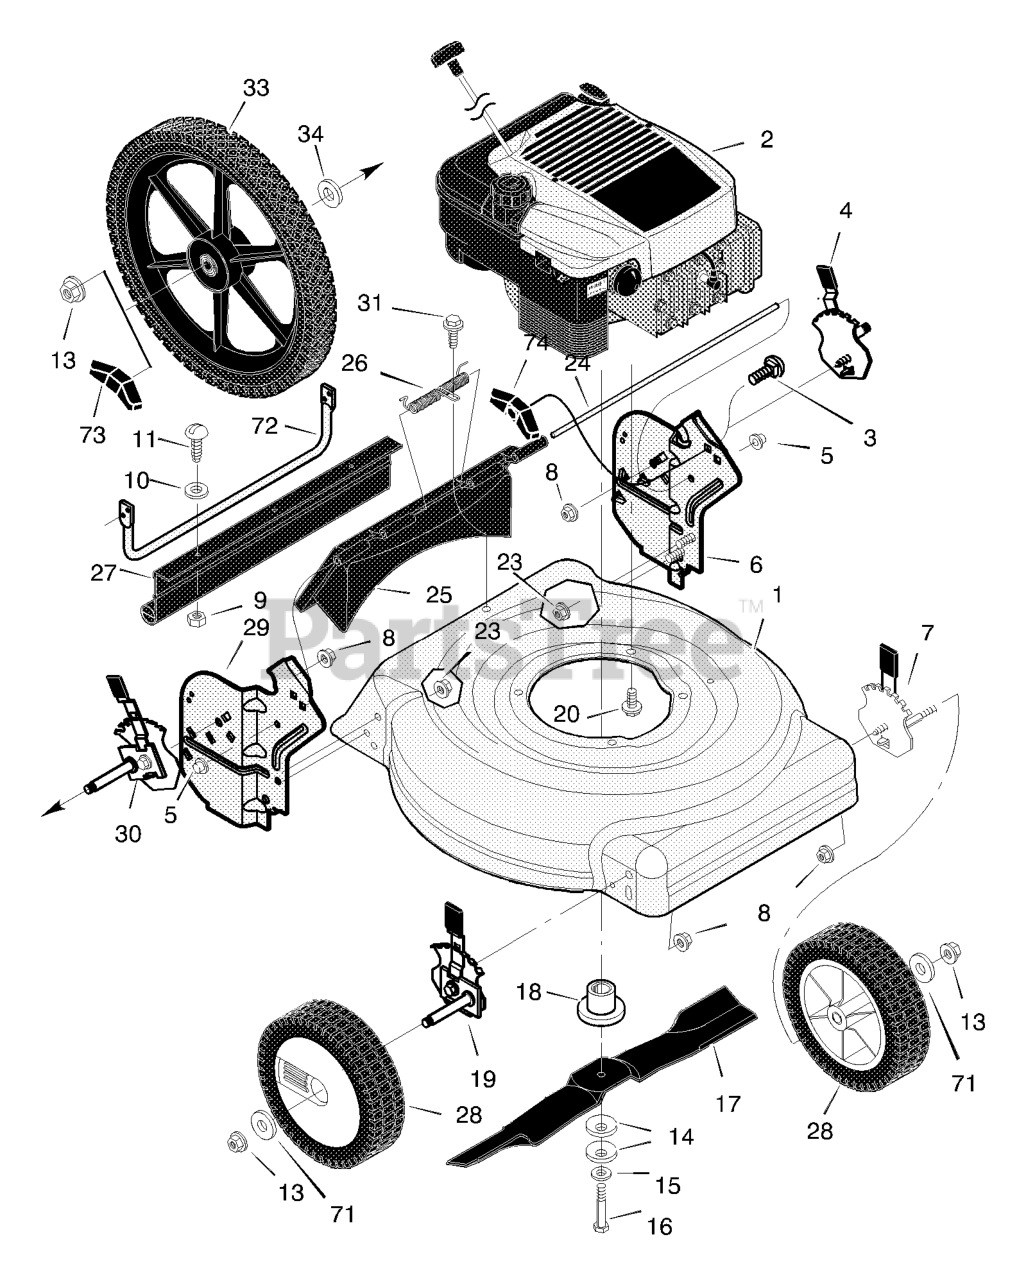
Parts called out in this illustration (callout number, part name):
1	Housing
2	Engine
3	Bolt, Carriage
4	Adjuster, Left Rear Height
5	Push On Cap
6	Bracket, Left Handle
7	Adjuster, Left Front Height
8	Nut, Flange
9	Nut, Hex
13	Nut, Flange
14	Washer, Belleville
18	Adapter, Blade
19	Adjuster, Right Front Height
20	Bolt, Engine
23	Nut, Flange
24	Rod, Pivot
25	Door, Rear (Black)
27	Guard, Rear
28	Wheel & Tire
29	Bracket, Right Handle
30	Adjuster, Right Rear Height
33	Wheel, Rear
34	Washer
